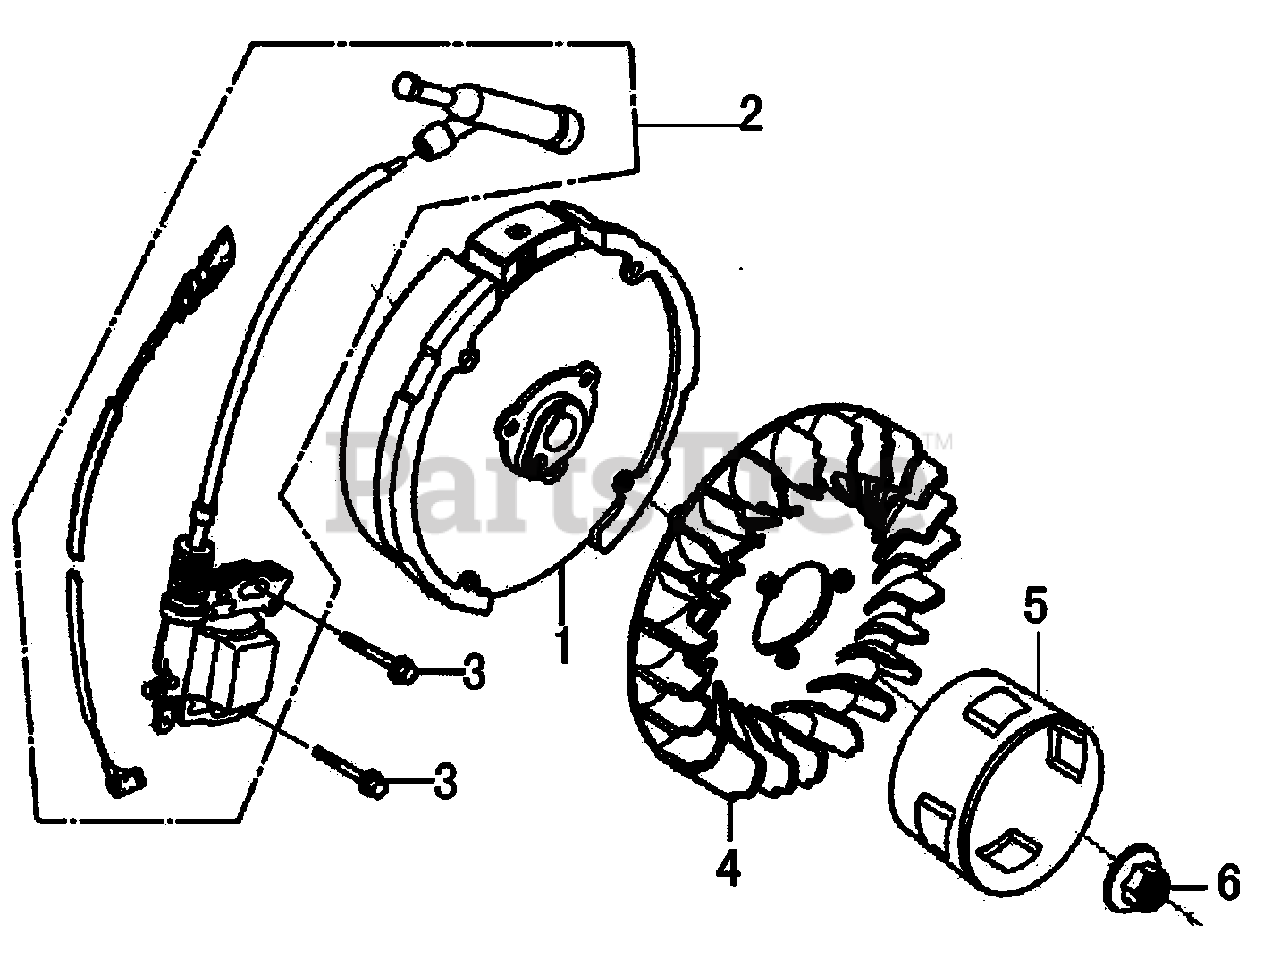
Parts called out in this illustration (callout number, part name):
2	COIL ASSY, IGNITION
3	BOLT, FLANGE 6X25
4	FAN, COOLING
5	PULLEY STARTER
